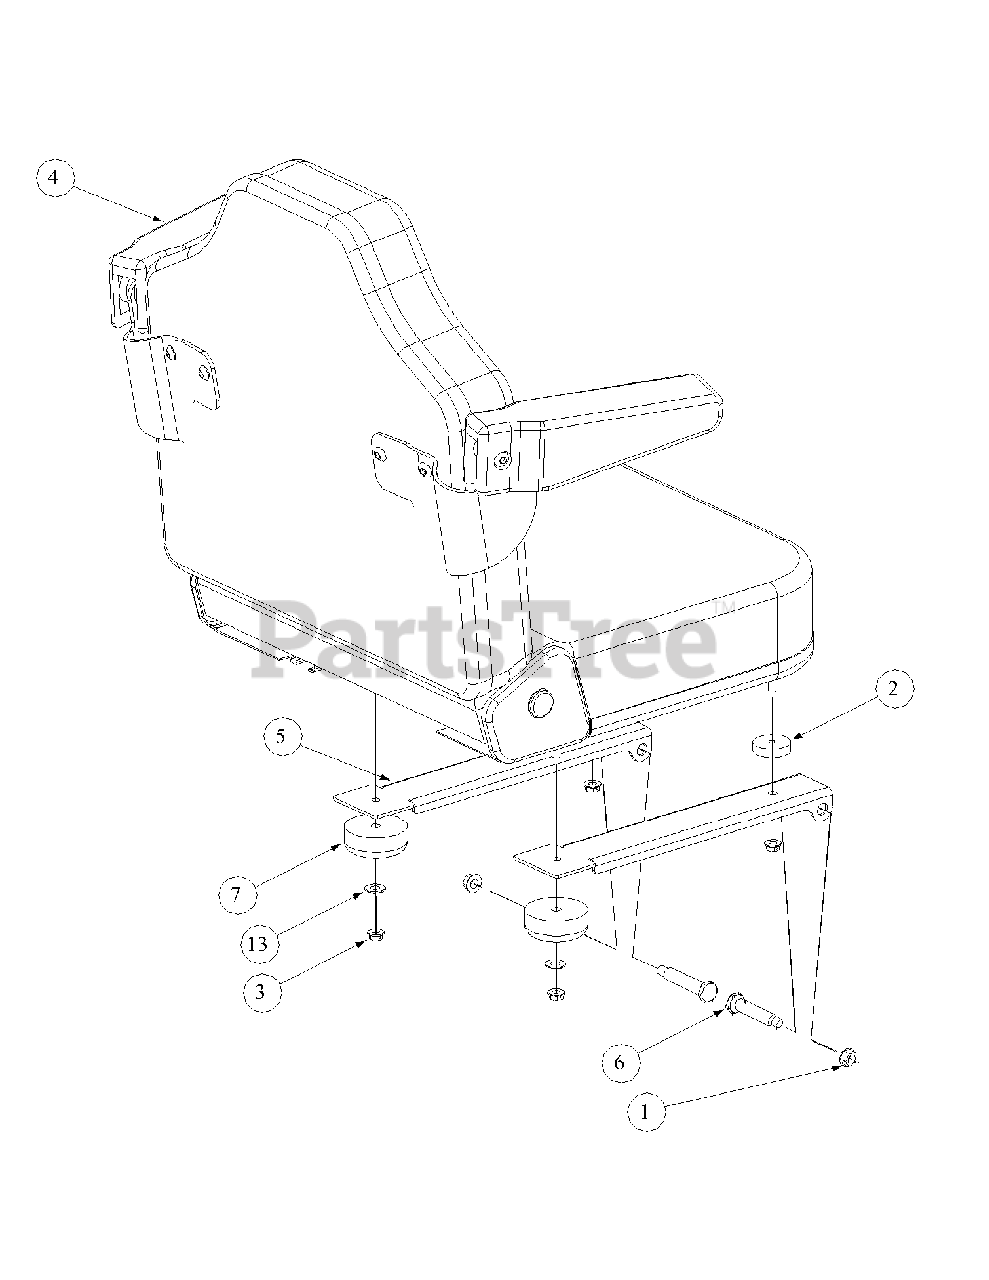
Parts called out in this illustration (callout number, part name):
1	Nut, Hex 3/8-16 Flange Lock
2	Spacer, 0.412 ID x 1.125 OD x .44
3	Lock Nut, Hex Flange, 5/16-18
4	Adjustable Seat, Black embossed, Forward Fold
5	Mounting Bracket, Seat
6	Shoulder Screw, .50x2.345, 3/8-16
7	Grommet, 2.5 OD x 1.0 Long
13	Washer
